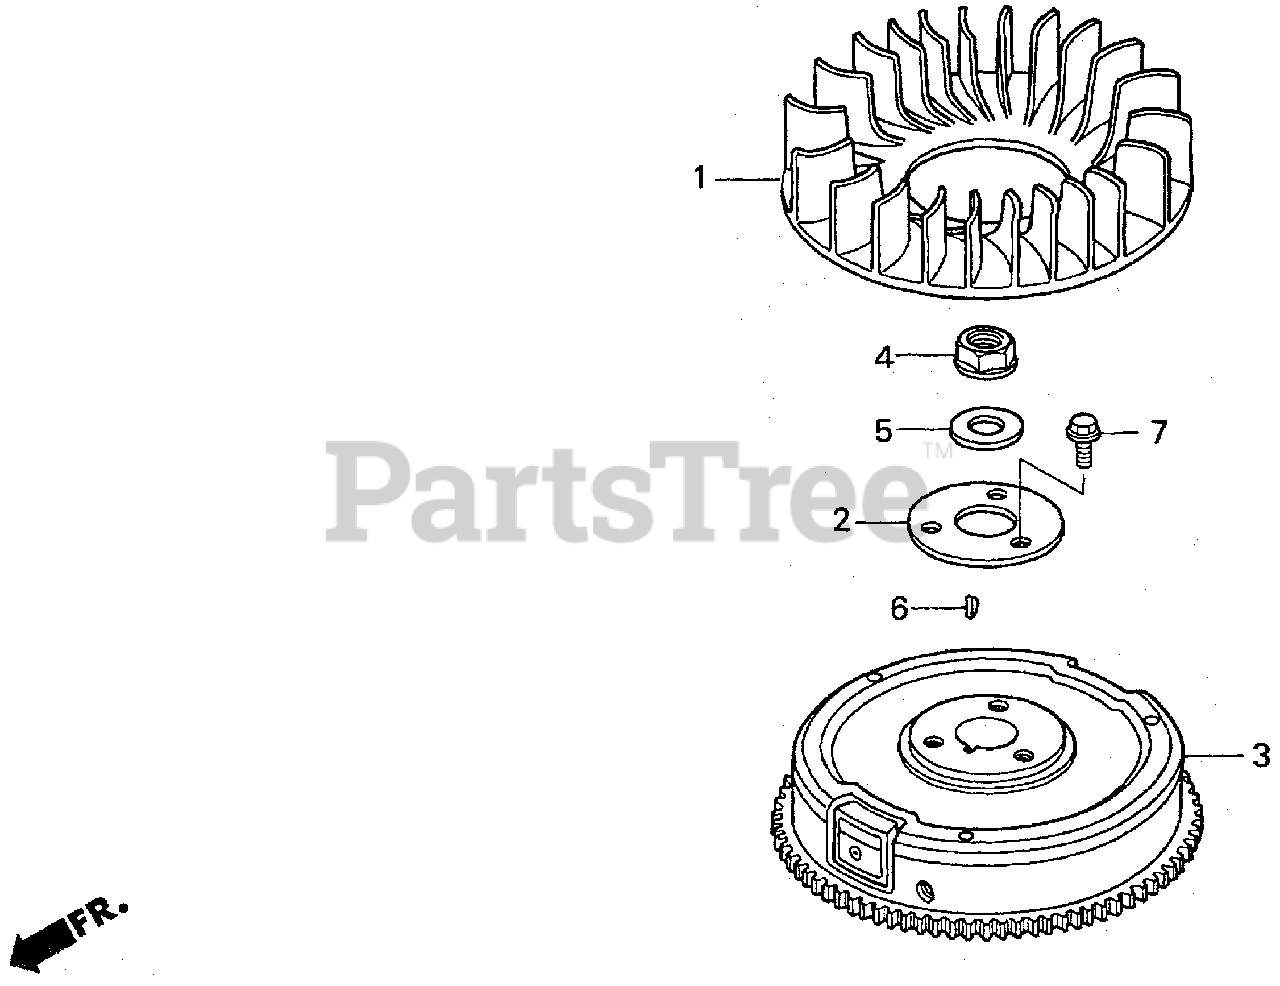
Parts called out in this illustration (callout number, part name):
1	FAN, COOLING
2	PLATE, COOLING FAN SETTING
4	NUT, FLANGE (20MM)
5	WASHER (20MM)
6	KEY, SPECIAL WOODRUFF (25X18)
7	BOLT, FLANGE (8X16)
